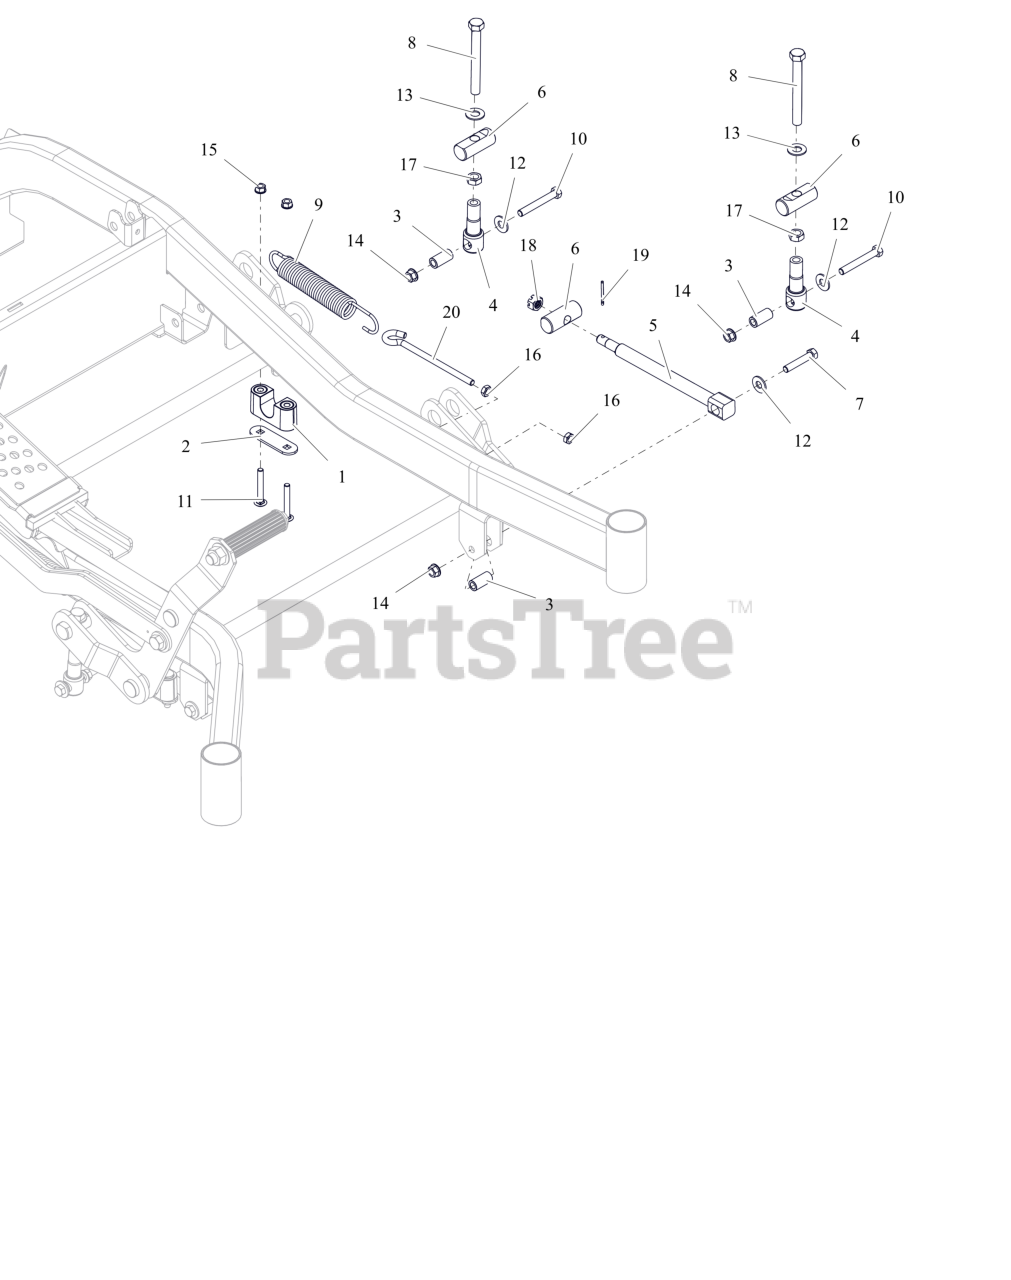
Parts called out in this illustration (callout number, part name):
1	ASM-BUSHING, DECK LIFT
2	PLATE, BEARING SUPPORT
3	SPACER, DECK LEVELING
4	LINK, DECK LIFT FORMED
5	DRAG,LINK-HD
6	PIN, DECK LIFT
7	BLT,HEX .38-16X2.00 G5 ZCC
8	BLT, HEX .50-13X4.50F G8 ZCC
9	SG-TENS .162X1.25X8.25 WLD 25
10	BLT, HEX .38-16X2.75 G8 ZCC
11	BLT, RHSSN.31-18X2.25 G5 ZCC
12	WSHR,FLT .438X1.00X.083 ZCC
13	WSHR, FLT .557X1.040X.102 ZCC
14	NUT-LK-TOP-FLG .38-16 ZC120
15	NUT,LK-CTR-FLG .31-18 GF ZCC
16	NUT-JAM .375-16 G2 ZCC
17	NUT-JAM .500-13 G2 ZCC
18	NUT-SL .50-13
19	PIN,CTR.12X1.25EXTPRSQCT ZC120
20	BOLT,.38-16 X 5.25-.62 DIA EYE
